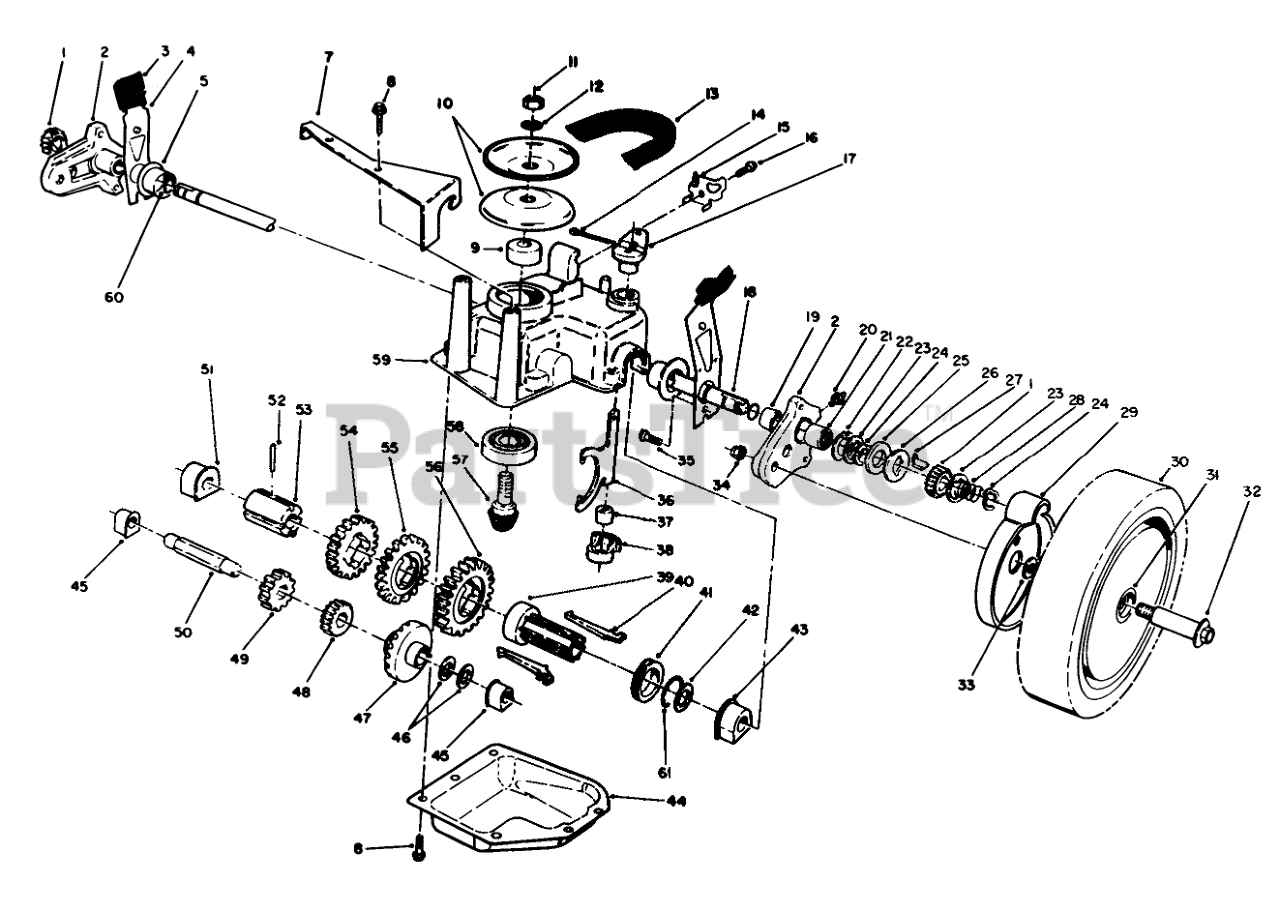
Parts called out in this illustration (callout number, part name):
1	GEAR-PINION
2	Pivot Arm Assembly (Incl. Ref #19, 20, & 21)
3	KNOB-ARM
4	SPRING ARM ASM SP
5	CAP-END
7	Bracket-Guide
8	SCREW-HWHTF
9	SPACER
10	Pulley Half
11	NUT-HEX
12	WASHER-FLAT
13	V-BELT E
14	PIN-COTTER
15	CLAMP-CABLE
16	SCREW-HWHTF
17	SHIFT LEVER
18	SHAFT-OUTPUT
19	BUSHING
20	FITTING-GREASE
21	BEARING-ROLLER
22	WASHER-ARM, PIVOT
23	WASHER-THRUST, KEYED
24	RING-CLIP, LOCKING
25	RING-FRICTION
26	WASHER-CLUTCH
27	KEY-ROCKING, LH
28	SPRING-COMPRESSION
29	COVER-WHEEL
30	Wheel-Tire & Gear Ass-y (Incl. Ref. #31)
31	BUSHING
32	WHEEL BOLT
33	SPACER-COVER, WHEEL
34	Nut
35	SCREW-HWH
36	YOKE-SHIFT
37	BUSHING-YOKE
38	RETAINER-FORK, SHIFT
39	SLEEVE-KEY, SHIFT
40	KEY-SHIFT
41	COLLAR-SHIFT
42	WASHER-PLAIN
43	BUSHING-OUTPUT
44	Cover-Gearcase
45	BUSHING
46	WASHER-THRUST
47	Gear-Bevel
48	PINION-20T
49	PINION-25T
50	SHAFT-INTERMEDIATE
51	BUSHING
52	PIN-SPRING
53	SLEEVE-GEAR
54	GEAR-39T
55	GEAR-44T
56	GEAR-49T
57	Gear-Pinion
58	BEARING-BALL
59	CASE-GEAR, UPPER
60	O-RING
61	CLIP-SPRING
